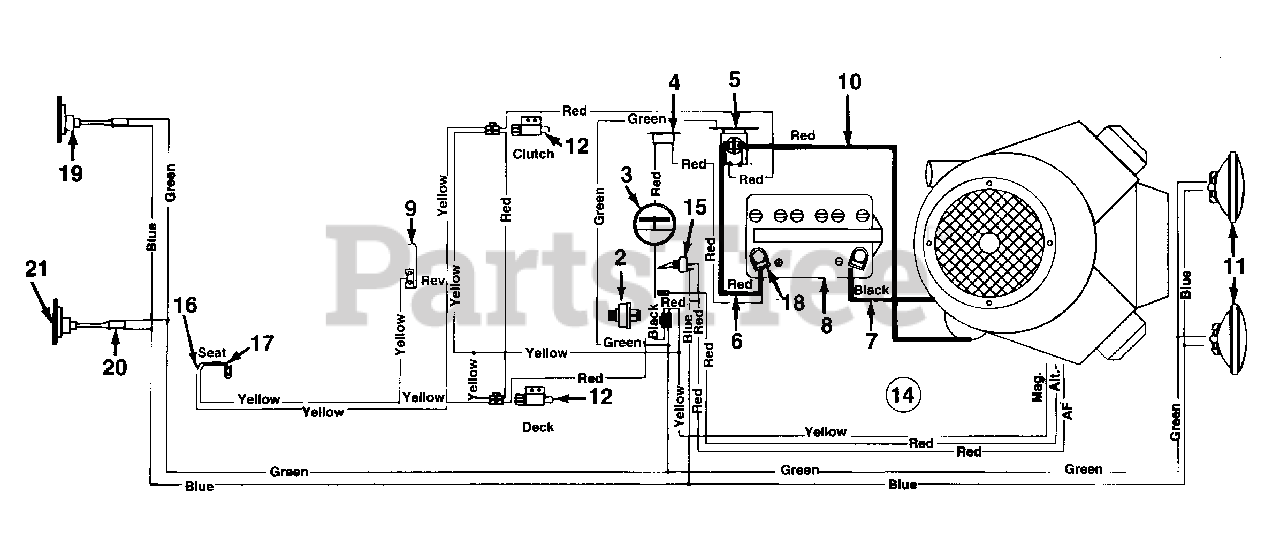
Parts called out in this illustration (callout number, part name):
2	Ignition Switch
3	Ammeter
4	Circuit Breaker 20 Amp
5	Solenoid
6	Electric Wire
7	Electric Wire
8	Battery
9	Spring Switch (Reverse Safety)
10	Electric Wire
11	Headlights
12	Safety Switch (PTO & Clutch)
14	Wire Harness
15	Light Switch
16	Safety Switch (Seat)
17	Safety Switch (Seat)
18	Battery Boot
19	Taillight
20	Taillight Harness
21	Taillight Bulb
